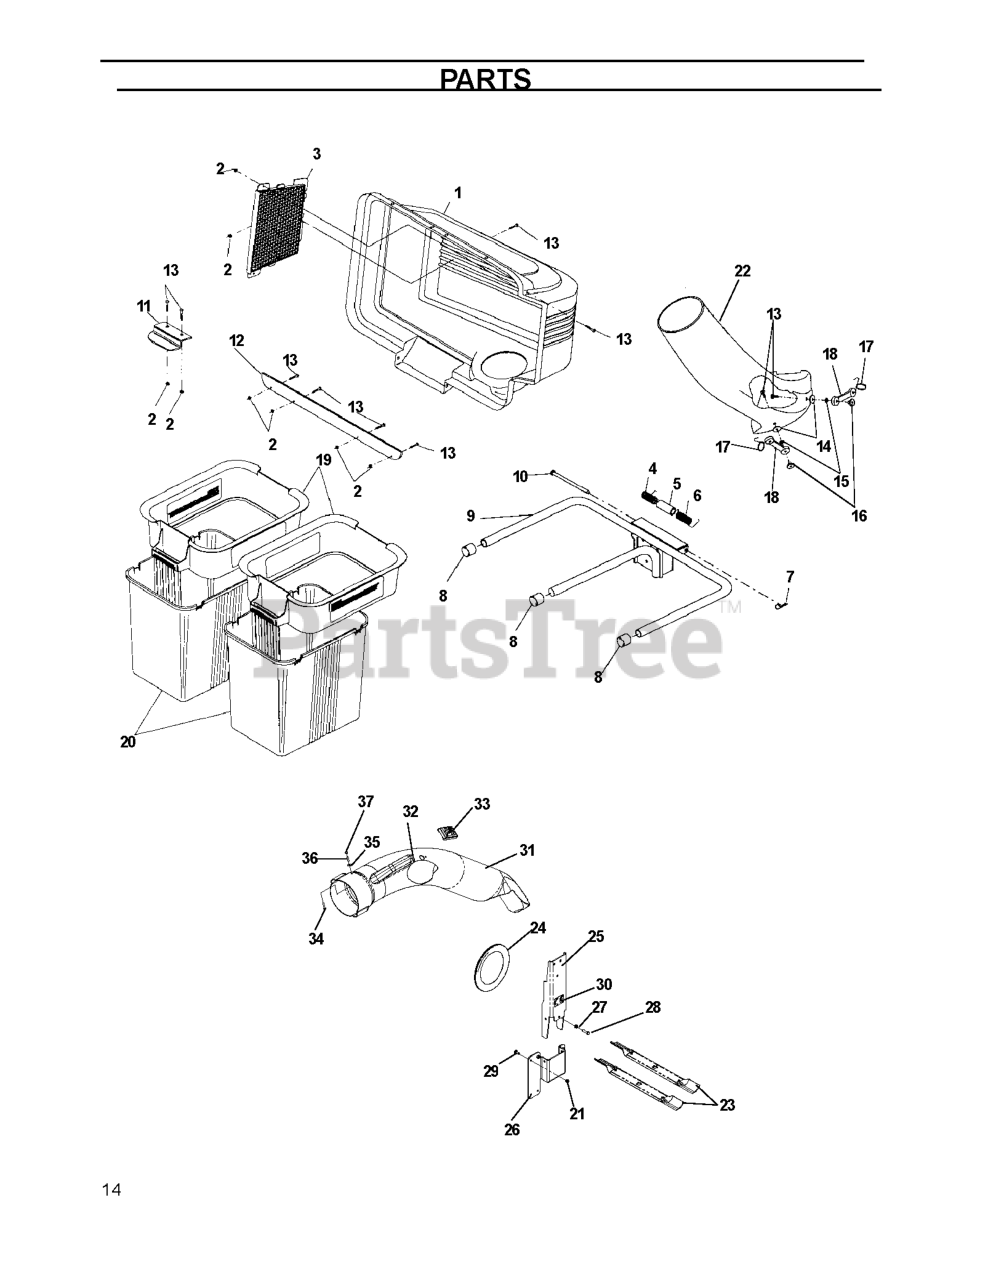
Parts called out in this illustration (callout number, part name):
3	Seals
9	Gaskets
20	Seals
22	Screws
